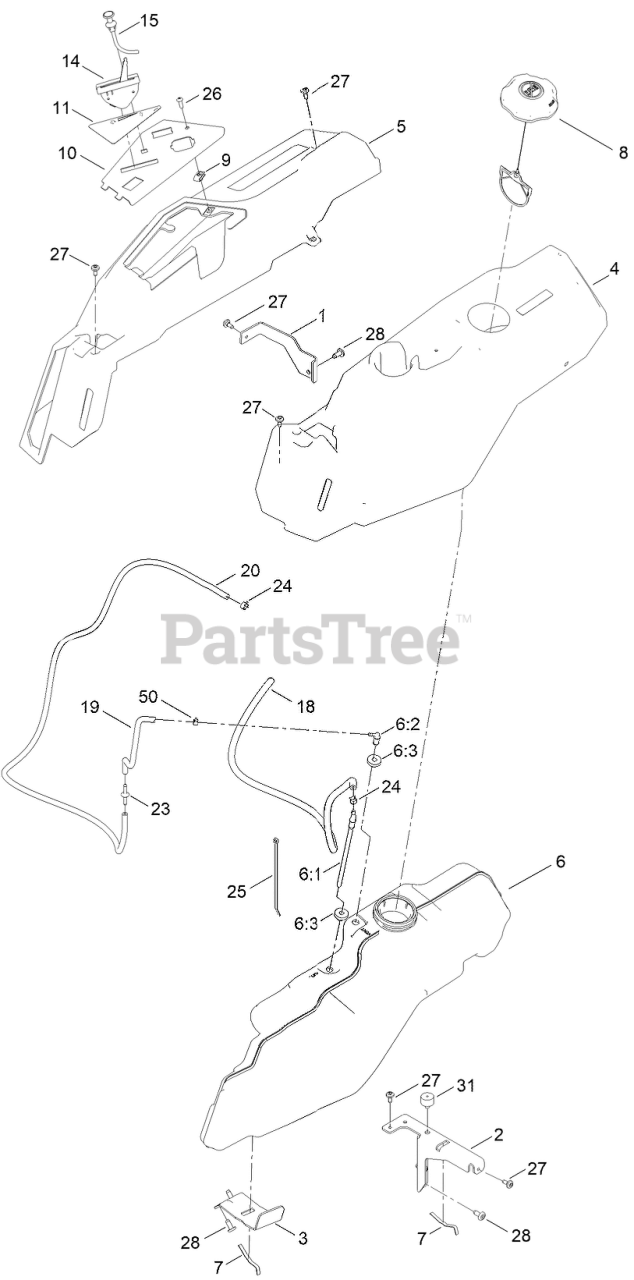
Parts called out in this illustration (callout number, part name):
1	BRACKET-POD
2	SUPPORT-POD, LH
3	SUPPORT-TANK, FUEL
4	POD-LH
5	POD-RH, MYRIDE
6	TANK-FUEL ASM
6:1	CONNECTOR-ELBOW, 90 DEG
6:2	FITTING-ELBOW 90
6:3	BUSHING
7	SPRING
8	CAP-FUEL, RATCHETING
10	PANEL - CONTROL
11	DECAL-PANEL, CONTROL
14	CABLE-THROTTLE
15	CABLE-CHOKE
18	HOSE-FUEL
19	HOSE-FUEL
20	HOSE-FUEL
23	ADAPTER ORIFICE
24	CLAMP-HOSE
25	TIE-CABLE
26	SCREW-PRH
27	SCREW-SHOULDER
31	BUMPER-GROMMET
50	CLAMP-HOSE
